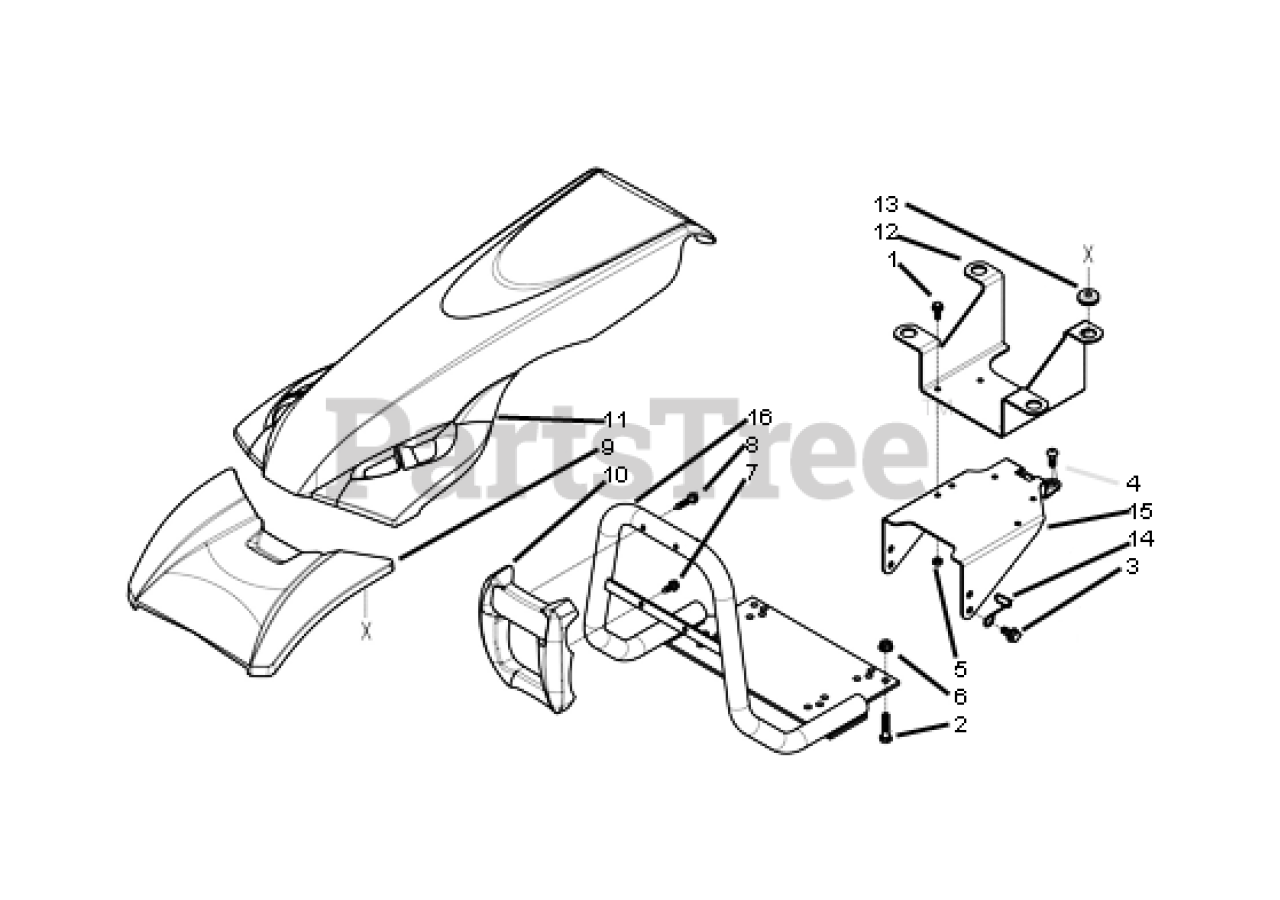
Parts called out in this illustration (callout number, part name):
1	SCREW HEX M6X16
2	CAPSCREW M8X40
3	SCREW M816
4	CAPSCREW M8X40
5	NUT, LOCK M6 STANDARD
6	NUT, LOCK M8 FLANGED
7	SCREW, SELF TAPPING M6.3X38
8	SCREW, SELF TAPPING M6.3X19
9	LOWER GUARD
10	BUMPER GUARD
11	GUARD, LONG STEERING COLUMN
12	GUARD SUPPORT
13	GROMMET, GUARD SUPPORT
14	GUIDE, CABLE
15	SUPPORT
16	BUMPER HONDA GX390
